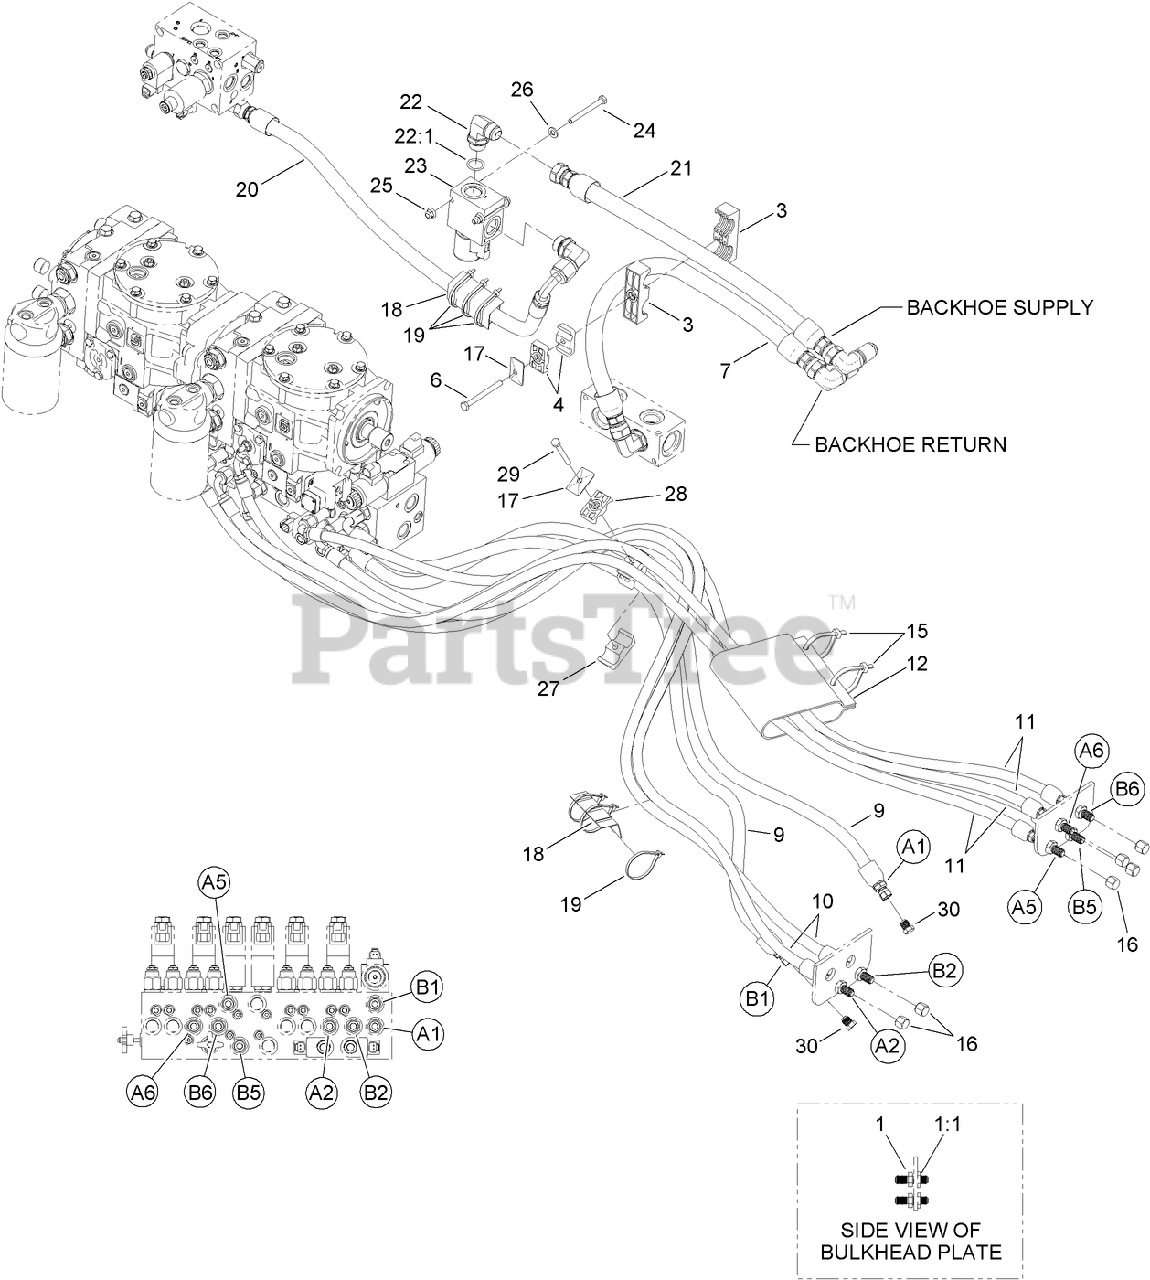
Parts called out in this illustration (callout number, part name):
1	UNION-BULKHEAD
1:1	NUT-LOCK, BULKHEAD
3	CLAMP-TWIN
4	CLAMP-TUBE
6	SCREW-HH
7	HYD HOSE ASM
9	HYD HOSE ASM
10	HYD HOSE ASM
11	HYD HOSE ASM
12	BOOT-HOSE
15	TIE-CABLE
17	COVERPLATE
18	PROTECTOR-HOSE
19	TIE-CABLE
20	HYD HOSE ASM
21	HYD HOSE ASM
22	FITTING-ELBOW, 90 DEG
22:1	O-RING
23	VALVE-BLOCKING
24	SCREW-HH
25	NUT-LOCK, HHF
26	WASHER-PLAIN
27	CLAMP-TUBE
28	CLAMP-TUBE
29	SCREW-HH
